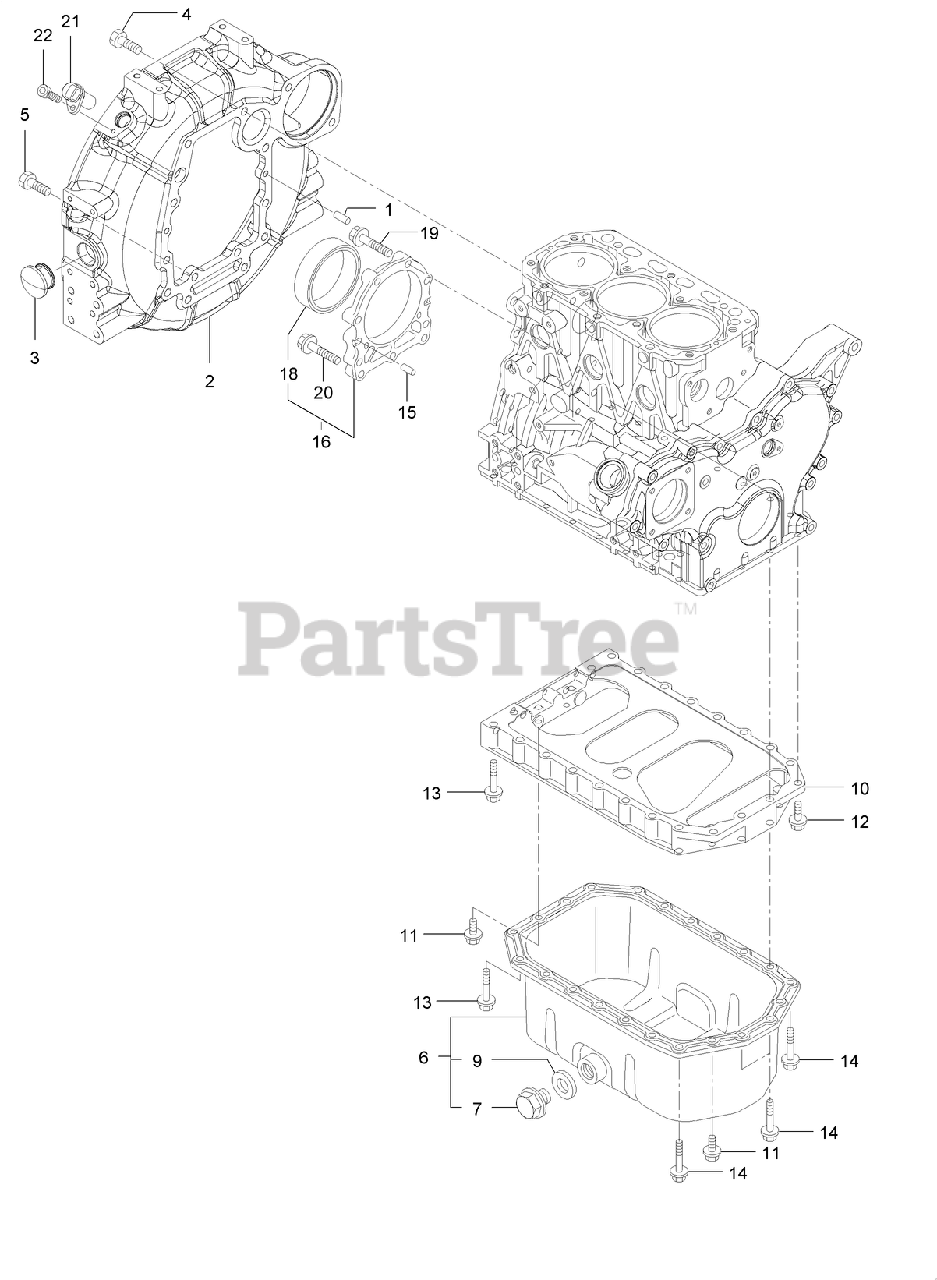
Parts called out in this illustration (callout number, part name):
2	HOUSING-FLYWHEEL
6	OIL PAN ASM
7	PLUG-DRAIN
9	WASHER-SEAL
10	SPACER
11	BOLT
16	CASE ASM
18	SEAL-OIL
21	SENSOR-REV, FLYWHEEL
